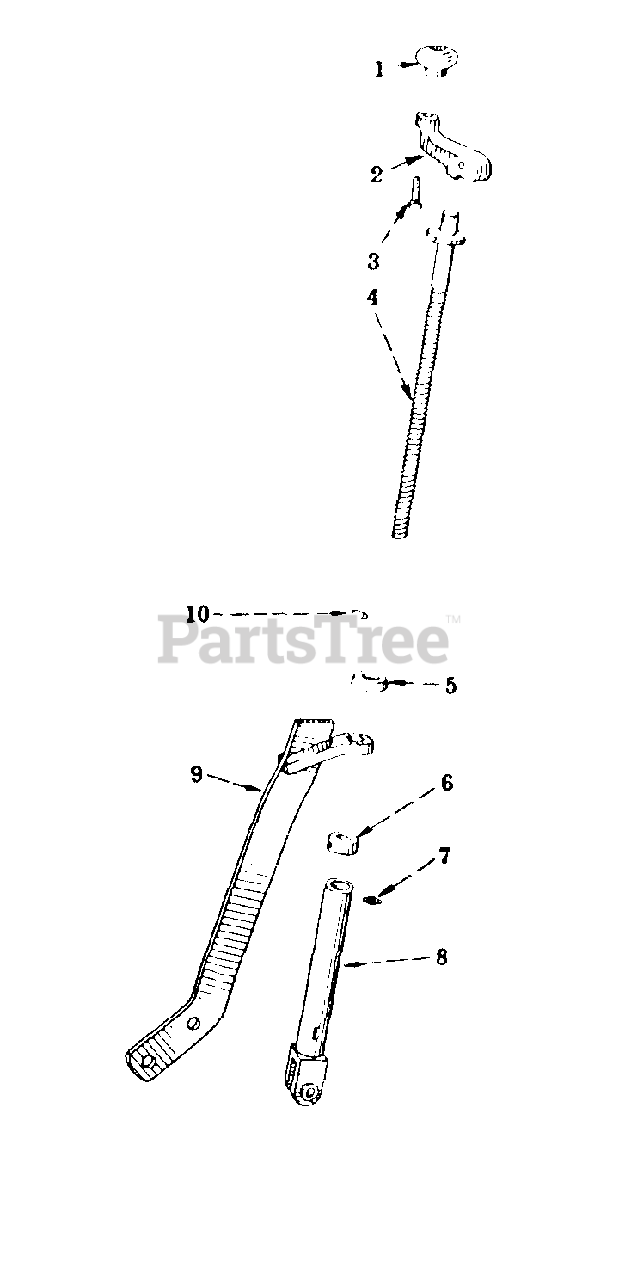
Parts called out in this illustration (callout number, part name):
1	KNOB, DEPTH ADJUSTING SCREW HANDLE
2	HANDLE, DEPTH ADJUSTING SCREW
3	PIN, 1/2 X 2-9/16 ESNA ROLL
4	SCREW ASSY, DEPTH ADJUSTING
5	BEARING, THRUST
6	COLLAR, DEPTH ADJUSTING SCREW
7	FITTING, 1/8-27 STR LUB
8	HOUSING, DEPTH ADJUSTING SCREW
9	SUPPORT ASSY, DEPTH ADJUSTING SCREW
10	PIN, 1/4 X 7/8 ESNA ROLL
